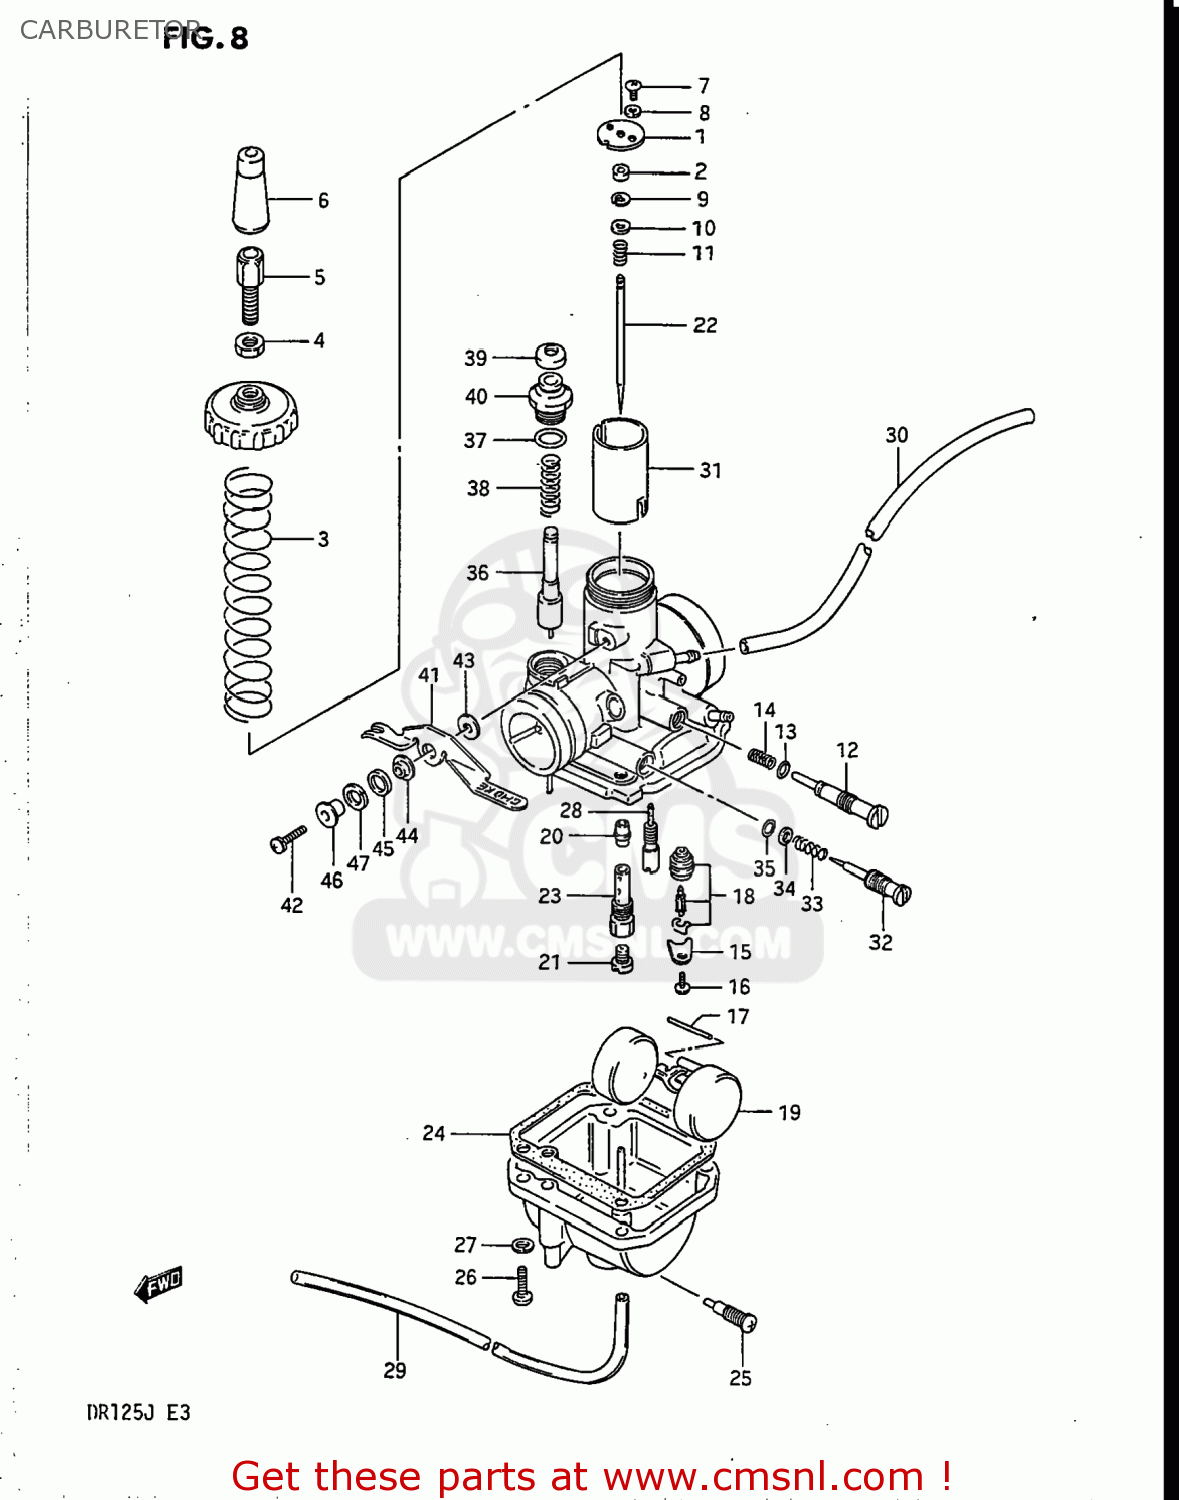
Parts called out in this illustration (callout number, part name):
1	PLATE
2	RING
3	SPRING
4	NUT
5	ADJUSTER,CABLE
6	CAP,RUBBER
7	SCREW
8	LOCK WASHER
9	CLIP
10	WASHER,JET NEEDLE
11	SPRING
12	SCREW,THROTTLE STOP
13	O RING
14	SPRING
15	PLATE,NEEDLE VALVE FITING
16	SCREW
17	PIN,FLOAT
18	VALVE ASSY,NEEDLE
19	FLOAT
20	JET,NEEDLE(N-8)
21	JET,MAIN
22	NEEDLE,JET
23	PIPE
24	GASKET (NAS)
25	PLUG,DRAIN
26	SCREW
27	WASHER,LOCK 4M
28	JET,PILOT(30)
29	HOSE
30	HOSE
31	VALVE,PISTON
32	SCREW,PILOT AIR
33	SPRING
34	GASKET
35	O-RING
36	PLUNGER ASSY
37	O RING
38	SPRING
39	CAP,STARTER VALVE
40	HOLDER
41	LEVER
42	SCREW
43	PLATE
44	RING
45	WASHER
46	RING
47	WASHER,LOCK,8.
